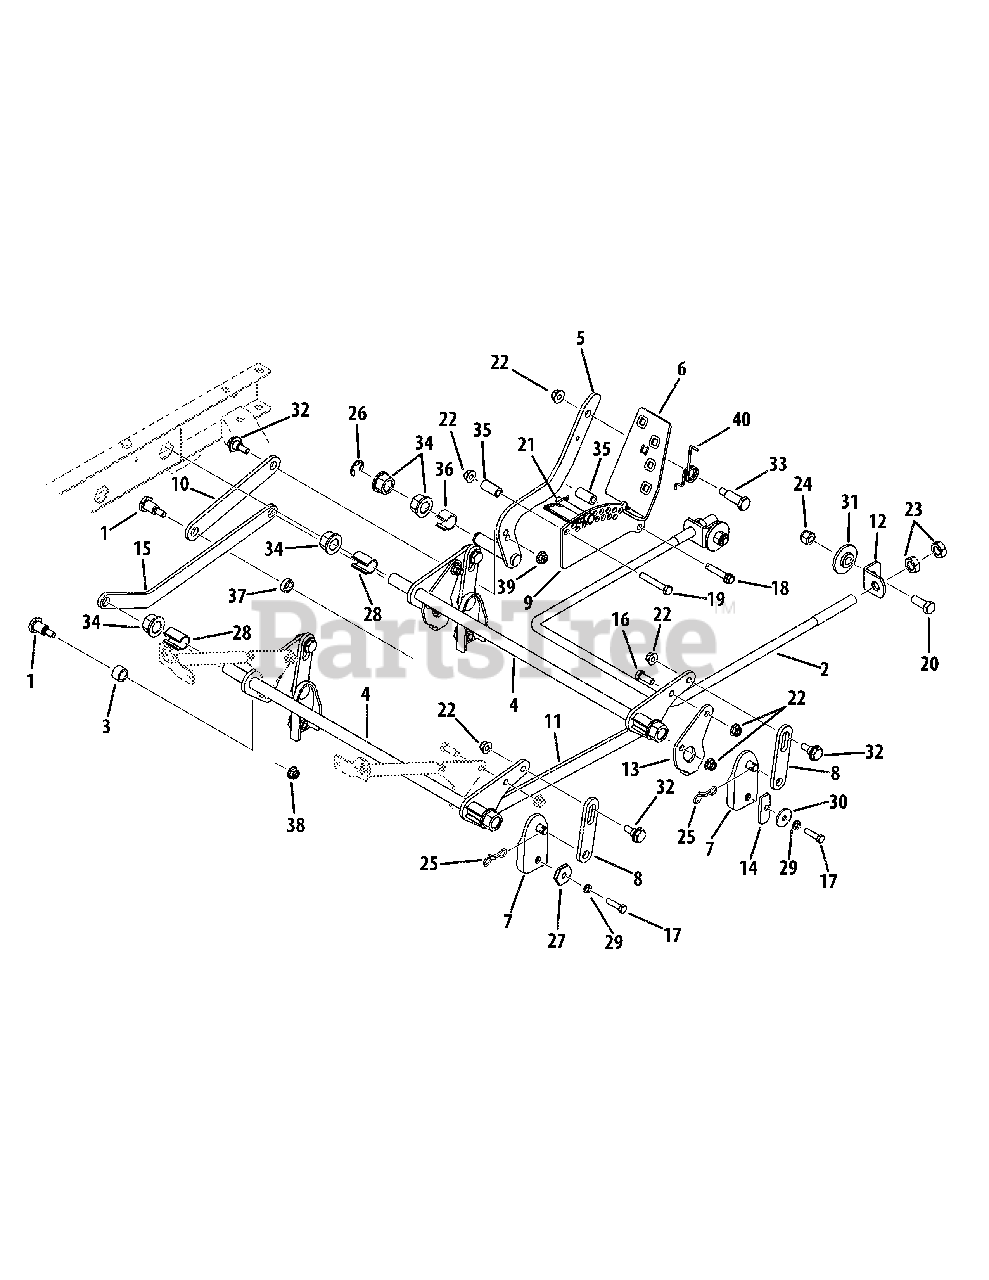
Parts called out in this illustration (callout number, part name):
1	Shoulder Screw, .625 x .830
3	Spacer, .632 x .877 x .548
4	Rock Shaft Assembly
5	Foot Lift Pivot Assembly
6	Lift Pedal Assembly
7	Deck Lift Adjustment Bracket
8	Lift Link Bracket
10	Pedal Link Plate
11	Mid Link Plate
12	Front Hanger Rod Bracket Mount
13	Deck Up Stop Bracket
14	Deck Lift Square Spacer
15	Mid-Angled Link Plate
16	Hex Screw, 3/8-16 x 1.00
17	Hex Screw, 5/16-18 x 1.25
18	Hex Washer Screw, 3/8-16 x 1.875
19	Hex Screw, 3/8-16 x 2.25
20	Hex Screw, 1/2-13 x 1.25
21	Lock Pin, .375 x 1.90
22	Flange Lock Nut, 3/8-16
23	Jam Nut, 1/2-13
24	Hex Lock Nut, 1/2-13
25	Click Pin, .092 x 1.64
26	E-Type Ring, .750
27	Adjustable Deck Gear
28	Spacer, .791 x .950 x 1.35
29	Lock Washer, 5/16
30	Flat Washer, .330 x 1.25 x .120
31	Shoulder Spacer, .9790 x .2025
32	Shoulder Spacer, 3/8-16 x .562 x .360
33	Shoulder Screw, .500 x 1.25 x 3/8-16
34	Hex Flange Bearing, .752
35	Spacer, .375 x .625 x 1.340
36	Spacer, .790 x .950 x .730
37	Spacer, .632 x .877 x .281
38	Flange Lock Nut, 7/16-20
39	Hex Lock Nut, 3/8-16
40	Torsion Spring, .75
